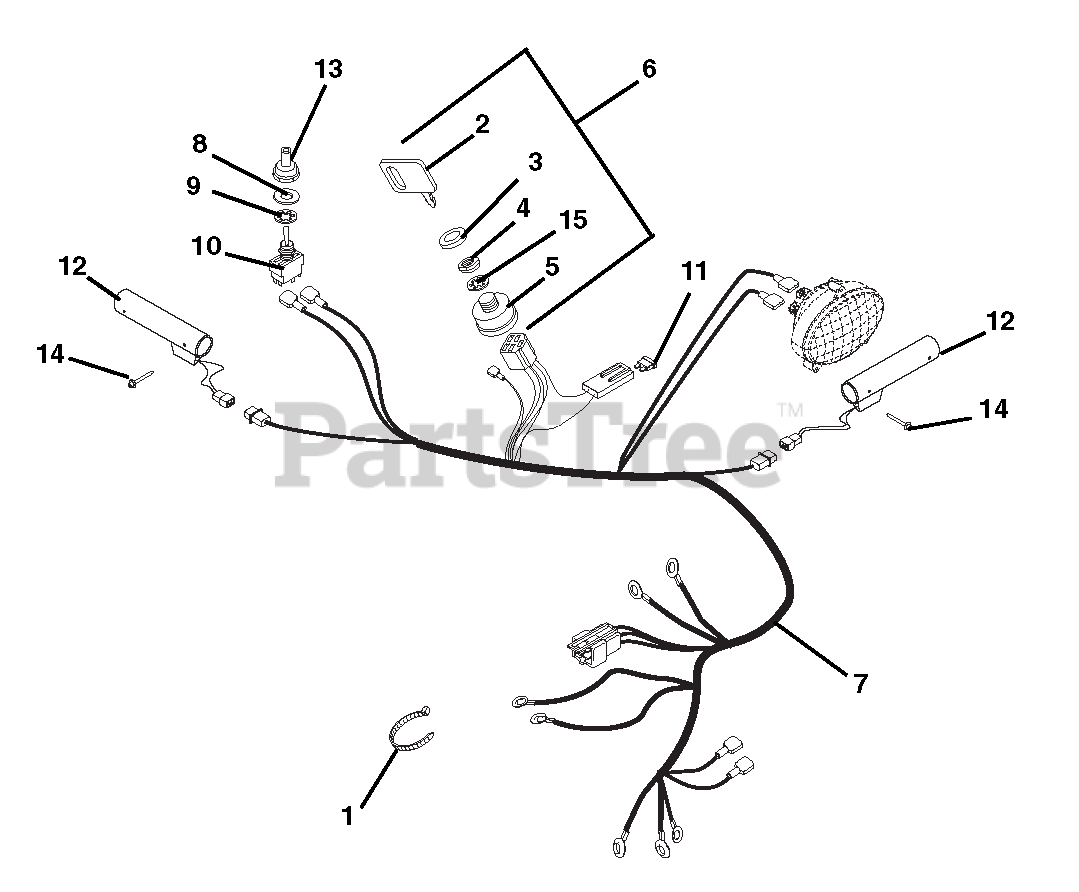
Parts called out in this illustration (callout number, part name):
1	CABLE TIE LG 5-1/2
2	KEY -W/CAP
3	CAP - IGNITION SWITCH
4	NUT-PANEL .625-32 GRECO
5	IGNITION SWITCH ASSEMBLY
6	SWITCH ASSEMBLY
7	HARNESS, WIRE-LIGHT&HANDWARMER
7	HARNESS, WIRE-LT, HW, & 12V
7	HARNESS, WIRE-LIGHT W/4 PIN
8	WSHR-FL-STL .505X.875X.024 PL
9	WSHR-LK-INT .563X.040 YWZC
10	SWITCH, ON/OFF
11	FUSE, 15 AMP.
12	HEATED GRIP, MAGURA
13	BOOT, SWITCH
14	RVT-POP #43 .125X.313 STL ZINC
15	WSHR-LK-INT .625X.045 YWZC
